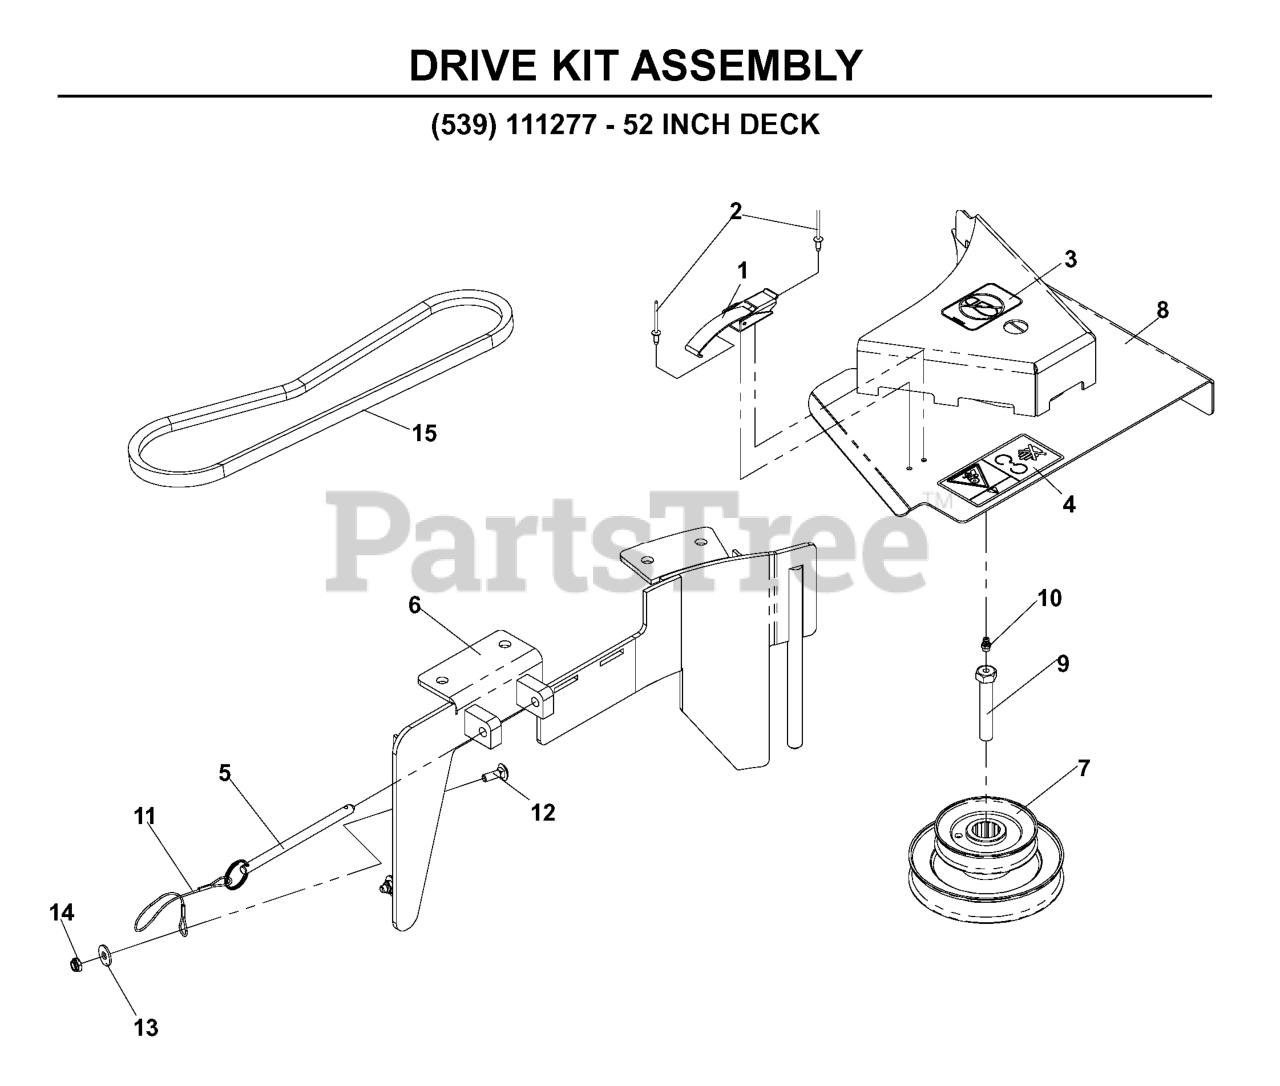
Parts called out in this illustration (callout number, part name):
1	DRAW LATCH
2	RIVET, BLIND, 5/32 DIA
3	DECAL, NO STEP
4	DECAL, BELT DRIVE
6	BLOWER DECK PLATE WLDMT, 52
7	52 LNG DOUBLE HEX STACK PULLEY
8	BELT SHIELD ASSY 52"
9	DRILLED BOLT 7/16-20 X 2 1/2"
10	ZERK
12	RHSNB 1/4C X 3/4
13	WASHER 1/4 FLAT
14	JAM NUT 1/4C (2 2 PW01)
